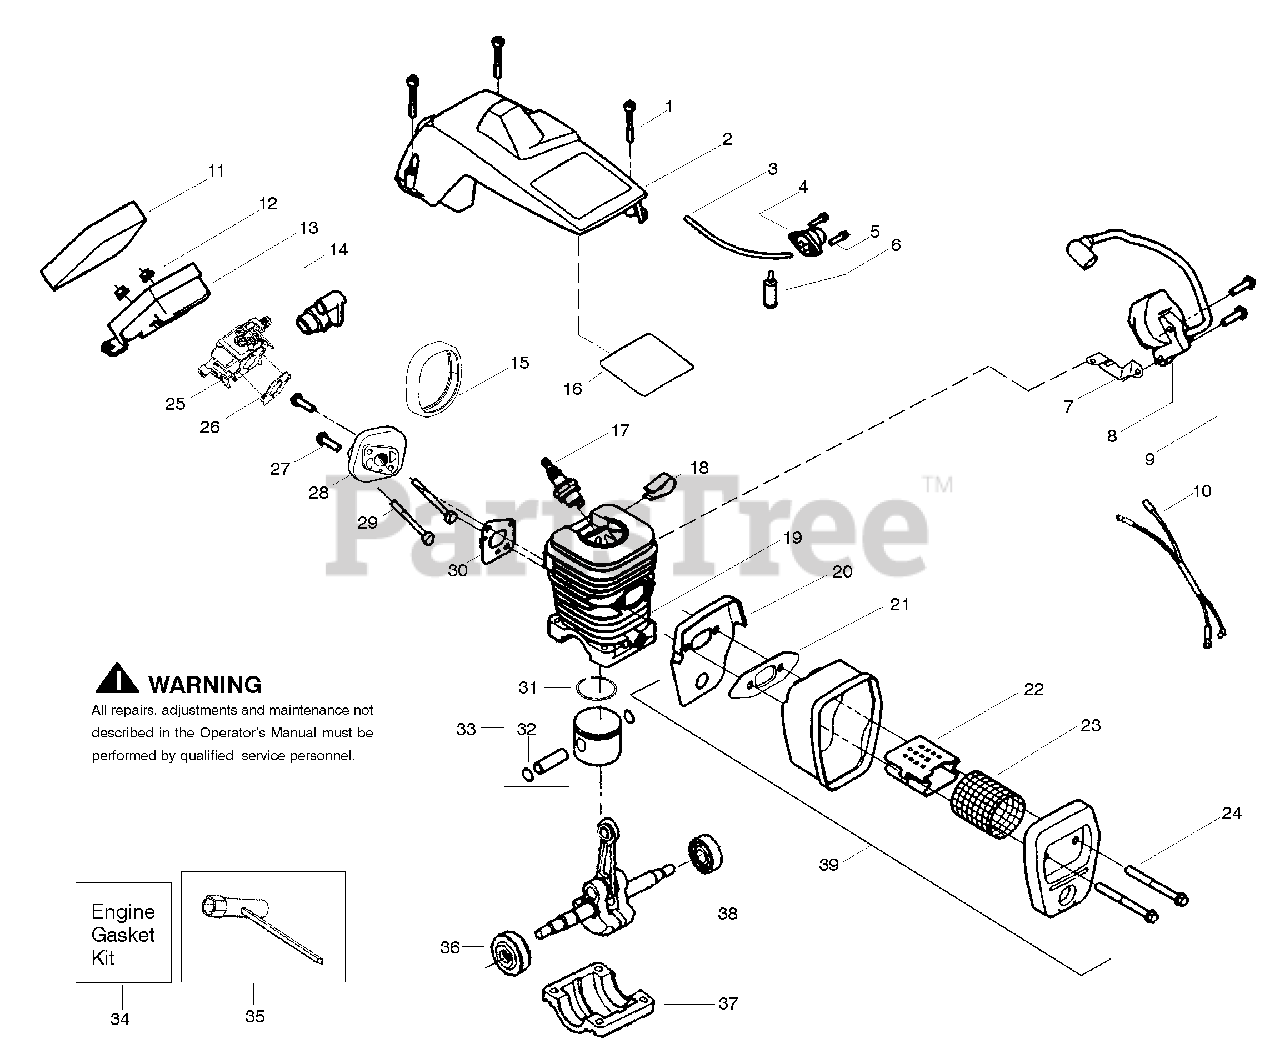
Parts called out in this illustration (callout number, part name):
2	Assy-Cylinder Shield
3	Kit-Fuel Line (Small)
4	Kit-Air Purge
6	Assy-Fuel Pick-up
7	Strap-Ground
8	Ignition Module
10	Assy-Wire Harness
11	Foam-Air Filter
13	Assy-Air Box
14	Grommet-Carb Adjust
15	Seal-Carb Adapter
16	Reflector-Heat
17	Spark Plug (RCJ-7Y)
18	Clip-High Tension Lead
19	Cylinder
20	Backplate-Muffler
21	Gasket-Muffler(kit)
22	Diffuser-Muffler
23	Screen-Spark
24	Bolt-Muffler
25	Kit-Carburetor (W-637)
26	Gasket-Carb. (kit)
28	Carb. Adapter
30	Gasket- Adaptor(kit)
31	Ring-Piston
32	Retainer-Piston Pin
33	Kit-Piston
34	Kit-Engine Gasket
35	Bar Wrench
36	Assy-Seal & Bearing
37	Cap-Crankcase
38	Assy-Crankshaft
39	Assy-Muffler
